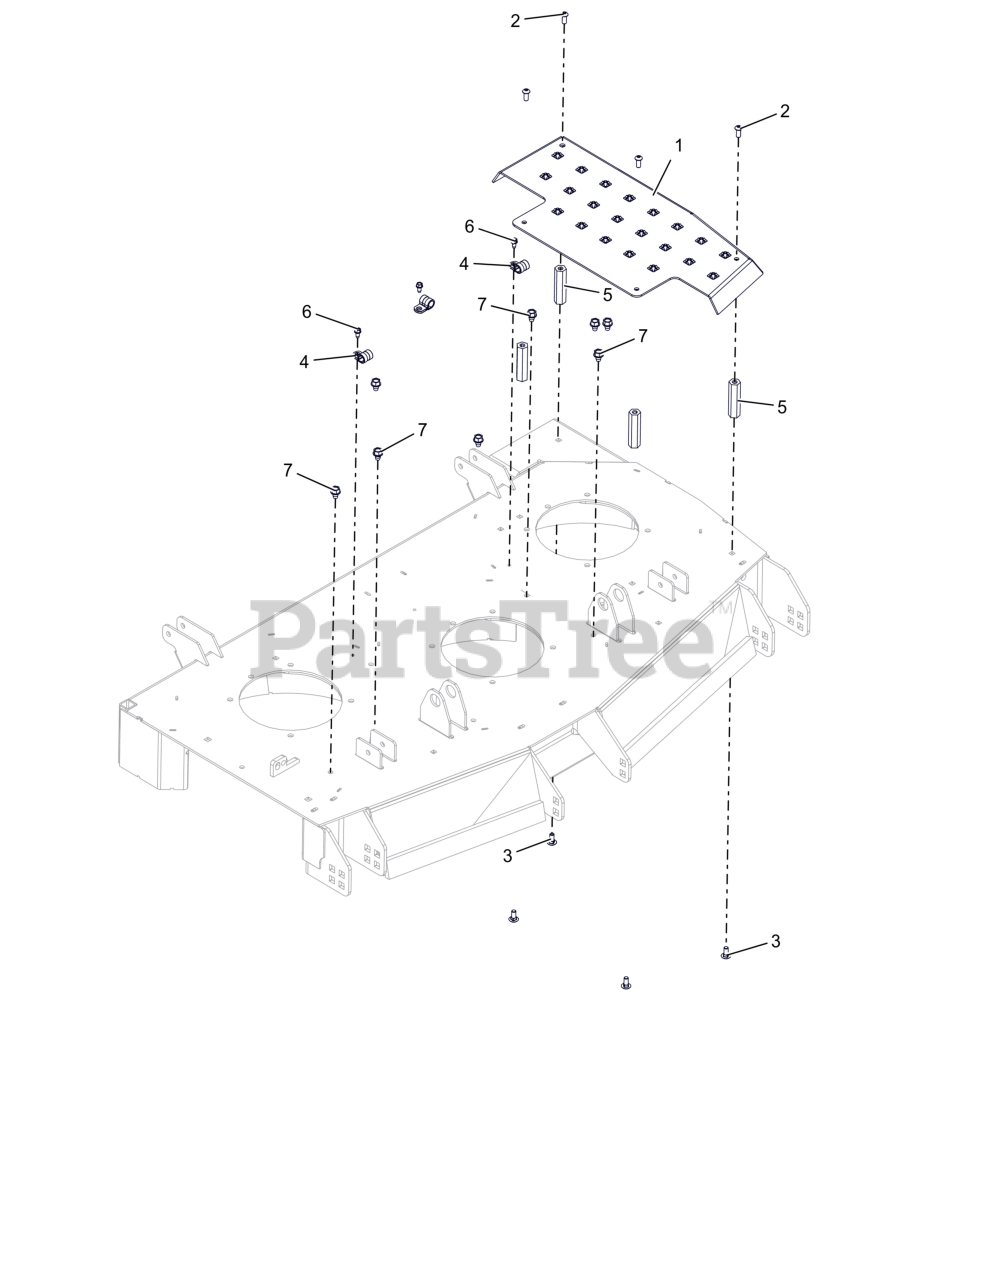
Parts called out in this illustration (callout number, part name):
1	PLATFORM, WLDMT 48 SD DECK STEP (RED)
2	SCR-SKH .31-18X.75 BTNHD YWZC
3	BTL,RHSN .313-18 X 0.75 G5 ZCC LT
4	CLAMP, CUSHIONED STEEL
5	NUT, COUPLING .31-18 X 3.00
6	SCR-TAP .25-20X.50 HWH ZCC
7	SCR,TAP .375-16X.50 HWH TR ZCC
